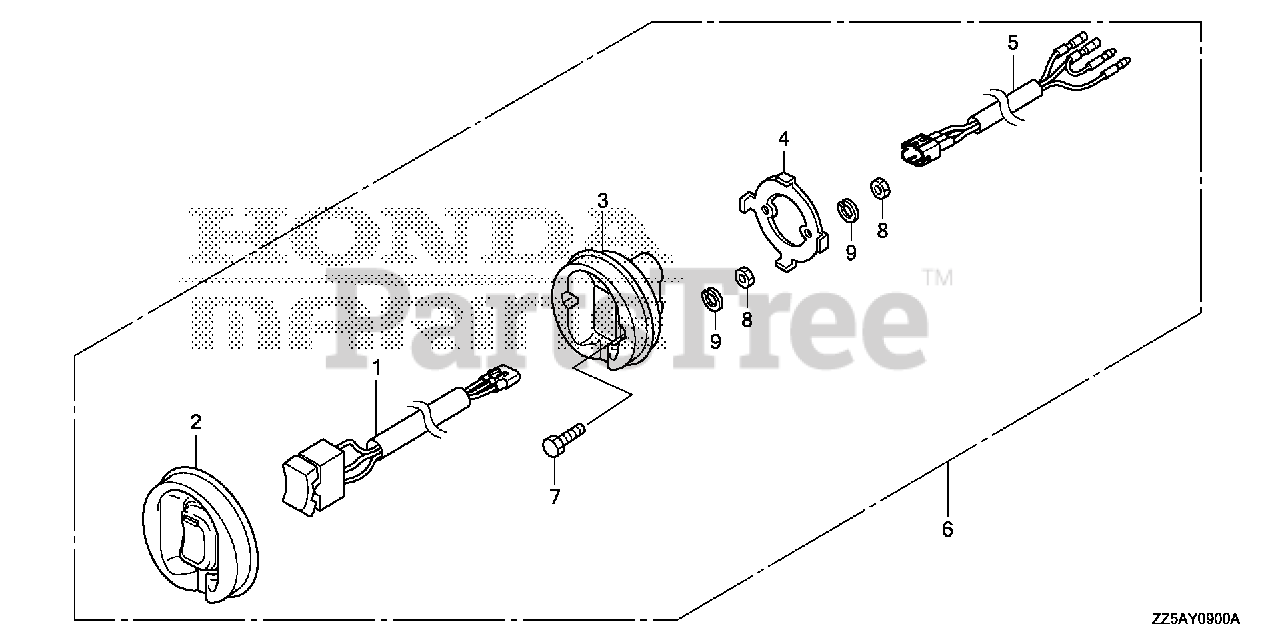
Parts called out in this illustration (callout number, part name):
1	SWITCH ASSY., TROLLING CONTROL (ENGINE NO.)
2	RUBBER, TROLLING CONTROL SWITCH PANEL (ENGINE NO.)
3	BODY, TROLLING CONTROL SWITCH PANEL (ENGINE NO.)
4	BRACKET, TROLLING CONTROL SWITCH PANEL (ENGINE NO.)
5	HARNESS, TROLLING CONTROL SWITCH PANEL (ENGINE NO.)
6	PANEL ASSY., TROLLING CONTROL (ENGINE NO.)
7	BOLT, HEX. (4X20) (ENGINE NO.)
8	NUT, HEX. (4MM) (ENGINE NO.) (NOT AVAILABLE)
9	WASHER, SPRING (4MM) (ENGINE NO.)
